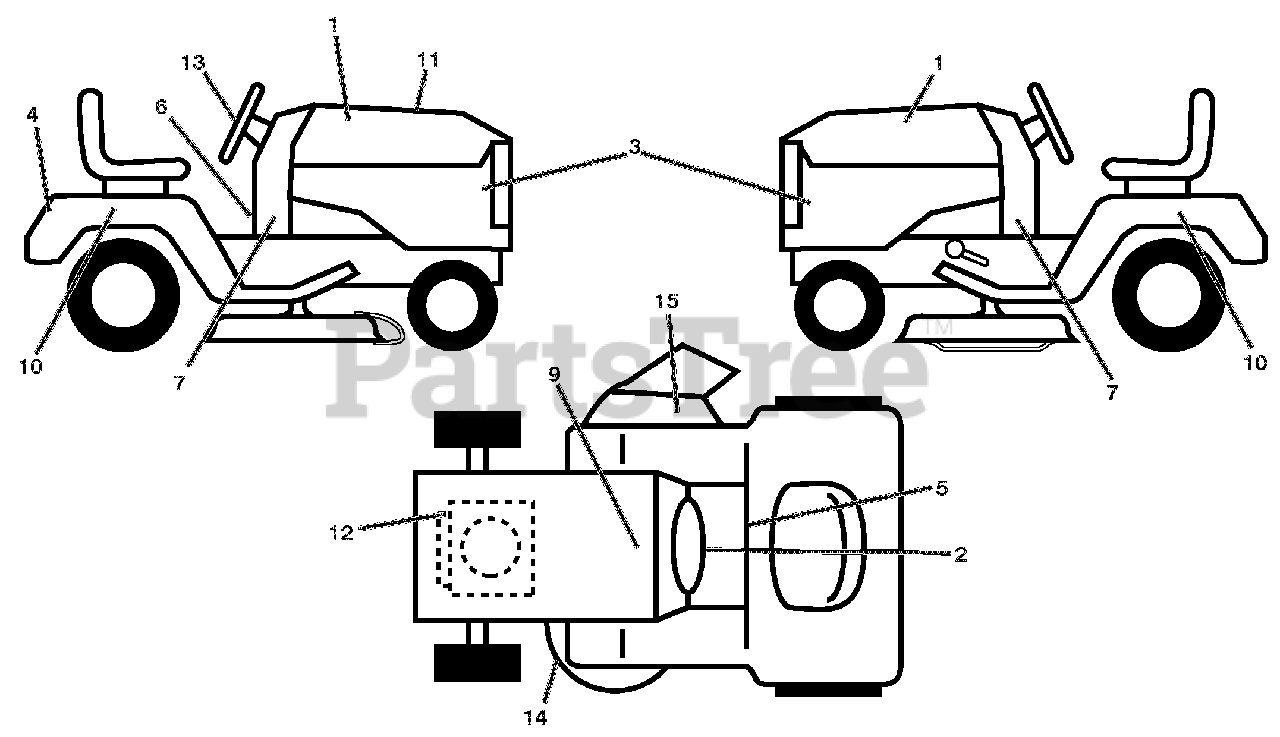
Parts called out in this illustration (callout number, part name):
1	DECAL.HOOD.LH/RH.
2	DECAL, FENDER WARNING
3	DECAL.SDPNL.PWRDBY B&S.ARIENS
4	DECAL.FENDER.REAR.ARIENS
5	DECAL.FENDER
6	DECAL.WARNING SPARK
7	DECAL, LOWER DASH
9	DECAL.BAT.DAN/POI P/L SYM.WPN
10	DECAL, FENDER SIDES
11	DECAL, REPLACEMENT
12	DECAL, ENGINE HP
13	DECAL.WHEEL.STEER.ARIENS
14	DECAL.V-BELT.SCH.
15	DECAL DECK/DEFLECT. WARNING
